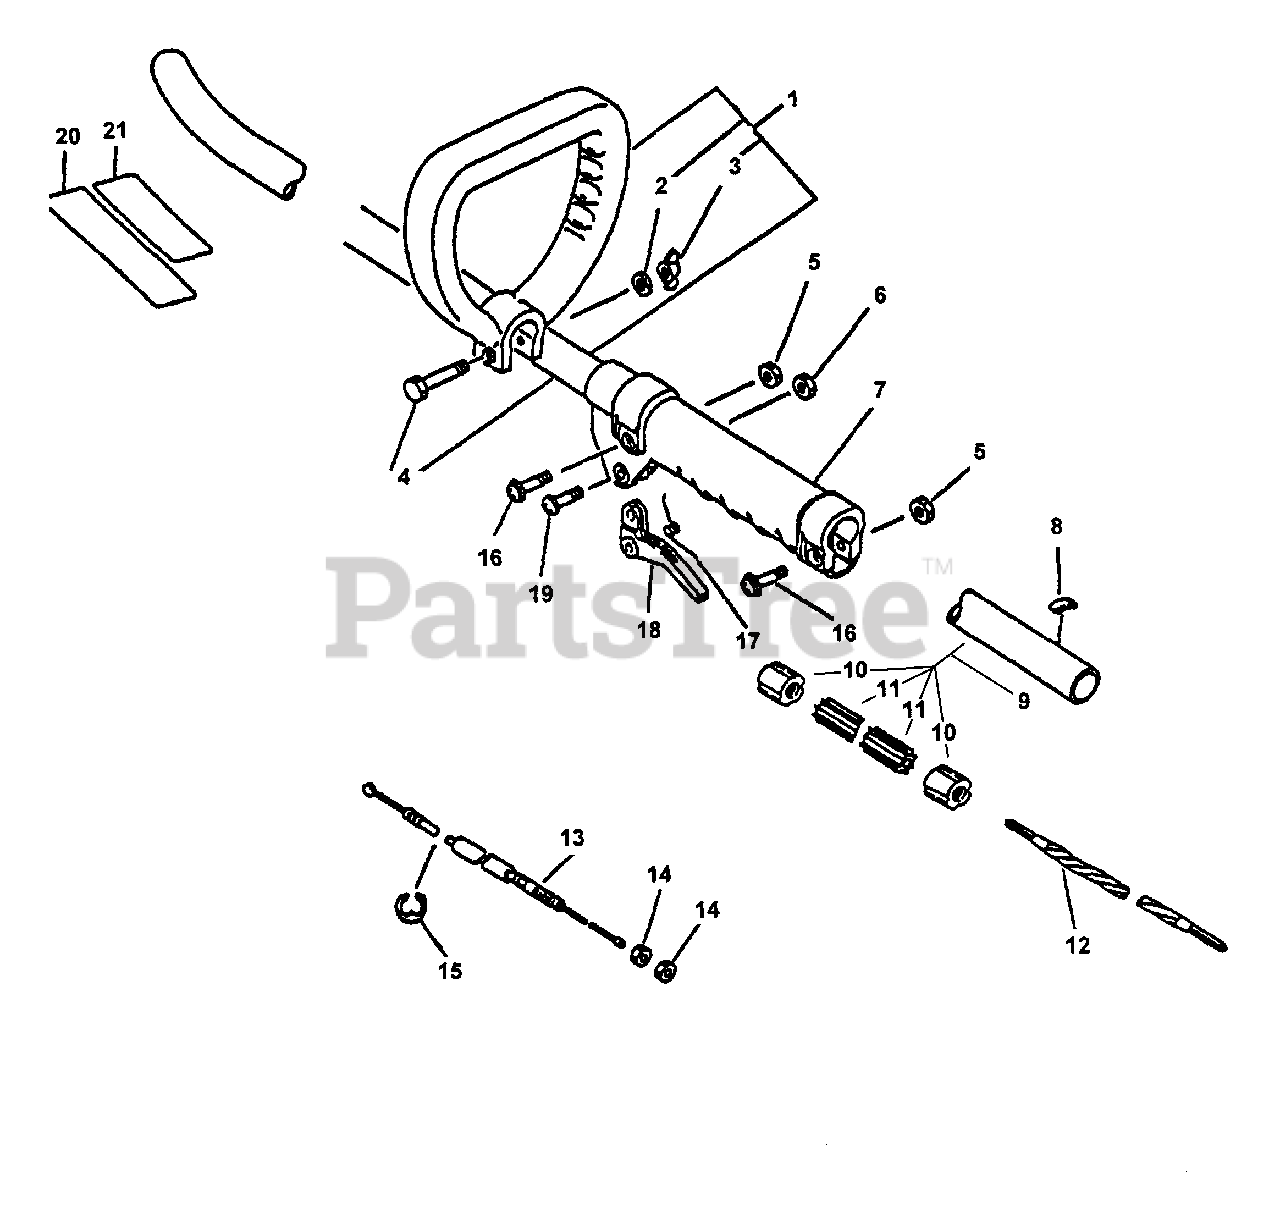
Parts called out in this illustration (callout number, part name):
1	HANDLE ASSY
2	WASHER 6.5×11.5×0.8
2	WASHER, 1/4"
3	NUT, WING 6
3	NUT, WING 1/4"-20
4	BOLT - 6×40
4	BOLT 1/4"-20×1-1/2"
5	NUT M5
6	NUT, LOCK M5
8	LABEL - ALIGNMENT
9	MAIN PIPE ASSY
11	LINER - FLEXIBLE
12	DRIVESHAFT - FLEXIBLE L= 1522
13	CABLE, THROTTLE
15	RING, RETAINING - 5
16	SCREW 5×25
17	SPRING, THROTTLE
18	TRIGGER, THROTTLE
20	LABEL, CAUTION
21	LABEL, CAUTION
